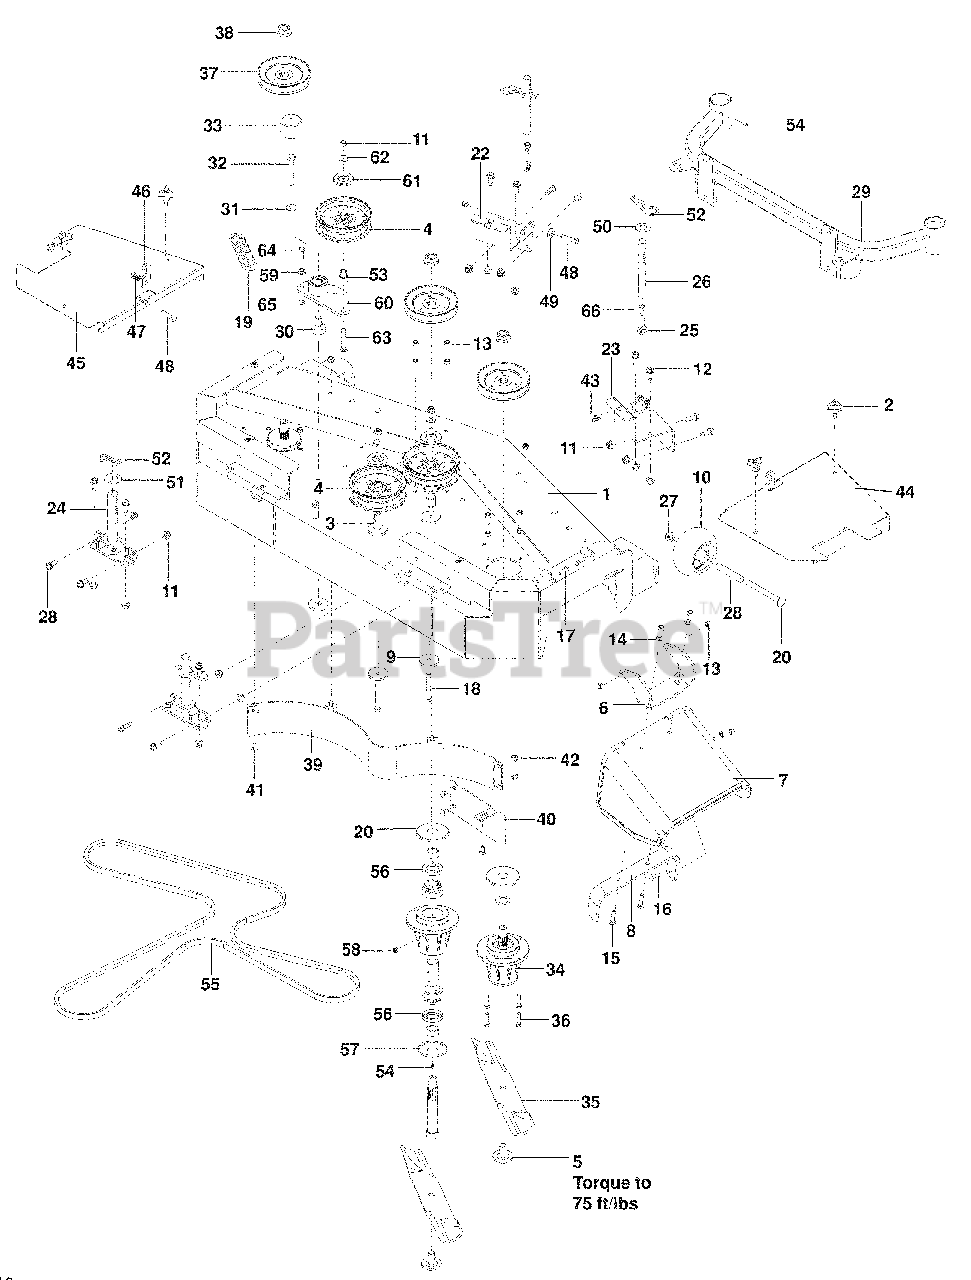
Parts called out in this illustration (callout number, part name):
1	CUTTER DECK w/ DECALS
2	KNOB w/ STUD
3	BUSHING, IDLER
4	PULLEY, IDLER
5	BLADE BOLT w/ WASHER
6	HINGE, CHUTE
8	REINFORCEMENT, BRKT
9	WASHER, HEAVY
10	ROLLER, GAUGE
11	NUT 3/8-16 FLG NYLOC
12	HCS 3/8-16 x 7/8
13	NUT 5/16-18 HEX NYLOC
14	WASHER 5/16 SAE FLAT
15	RHSNB 5/16-18 x 1½
16	RHSNB 5/16-18 x 1¼
17	HCS 5/16-18 x 1
18	HCS 3/8-16 x 3
20	RHSNB ½-13 x 4¾
22	SUPPORT, FRONT, LH
23	SUPPORT, FRONT, RH
25	ROD END 3/8-24 RH
27	NUT ½-13 HEX FLG NYLOC
28	TUBE, ROLLER
29	SUPPORT, CASTER
30	PIVOT, BEARING
31	WASHER ½" BELLEVILLE
32	HCS ½-13 x 3¼
33	CAP, VINYL
34	HOUSING ASSY
35	BLADE 16¼"
36	HCS 5/16-18 x 1¼
38	NUT ¾-16 FLANGE
40	BAFFLE, CENTER
41	RHSNB 5/16-18 x 5/8
42	NUT 5/16-18 HEX FLG NYLOC
43	RETAINER, U TYPE
47	SPRING, COMPRESSION
48	HCS 3/8-16 x 1½
49	WASHER 3/8 x ¾
50	WASHER ¾ FLAT SAE
52	HAIR PIN COTTER 3"
53	BUSHING, IDLER
55	BELT, DECK
56	SHAFT SEAL
57	BOTTOM DUST CAP
58	GREASE POPPET
59	NUT 3/8-16 HEX WHIZLK
60	ARM, IDLER w/ BEARINGS
61	SHIELD, DUST
62	WASHER 3/8 THICK
63	RHSNB 3/8-16 x 2¾
64	HCS 3/8-16 x 1½ GR 8
65	NUT 3/8-16 HEX JAM
66	NUT 3/8-24 HEX GR 2
